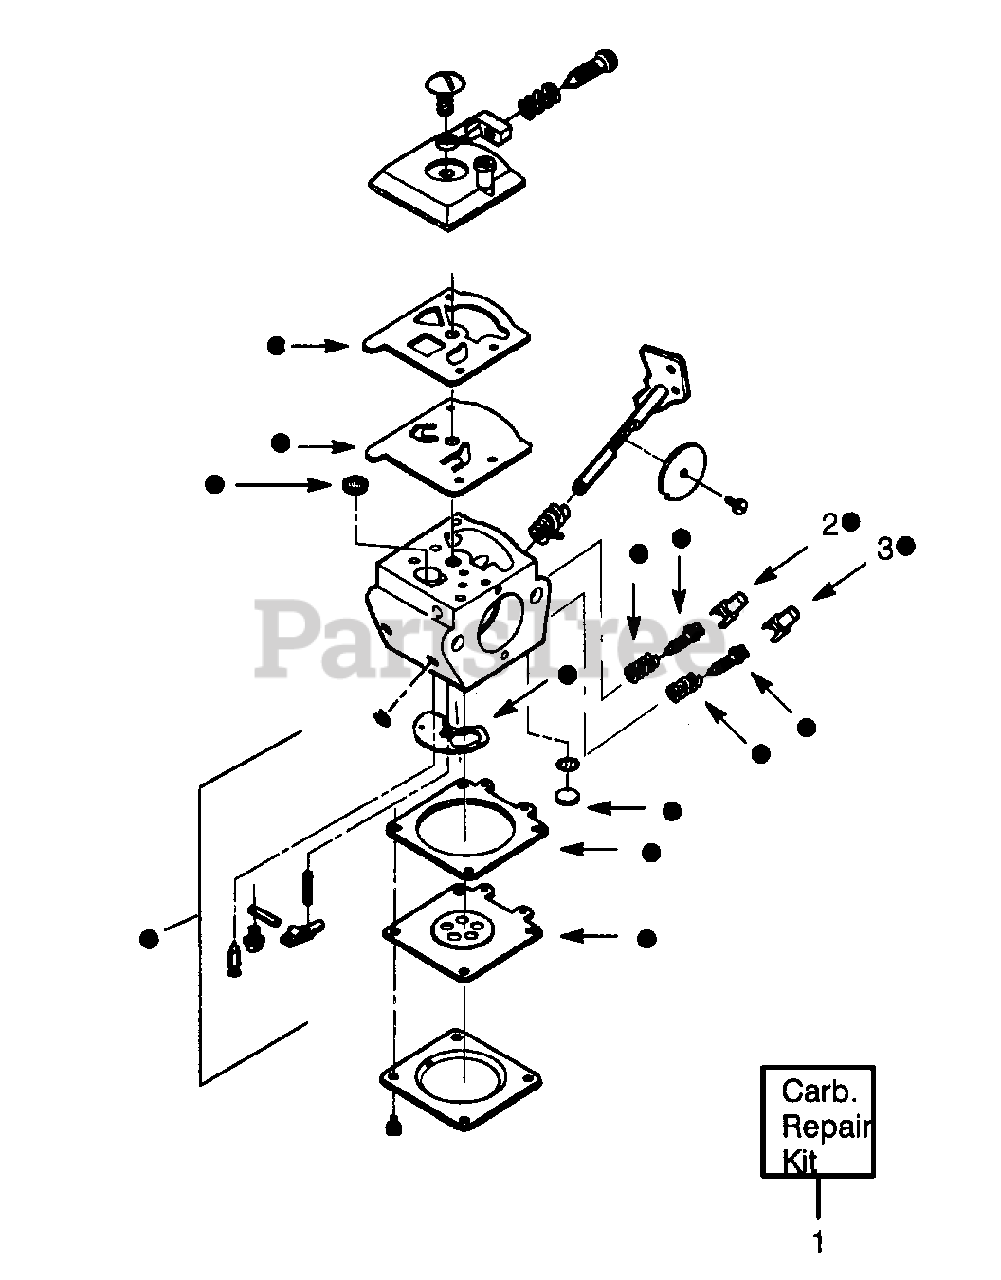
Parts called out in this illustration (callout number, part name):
1	Carburetor Repair Kit
2	Limiter Cap-Low
3	Limiter Cap-High
